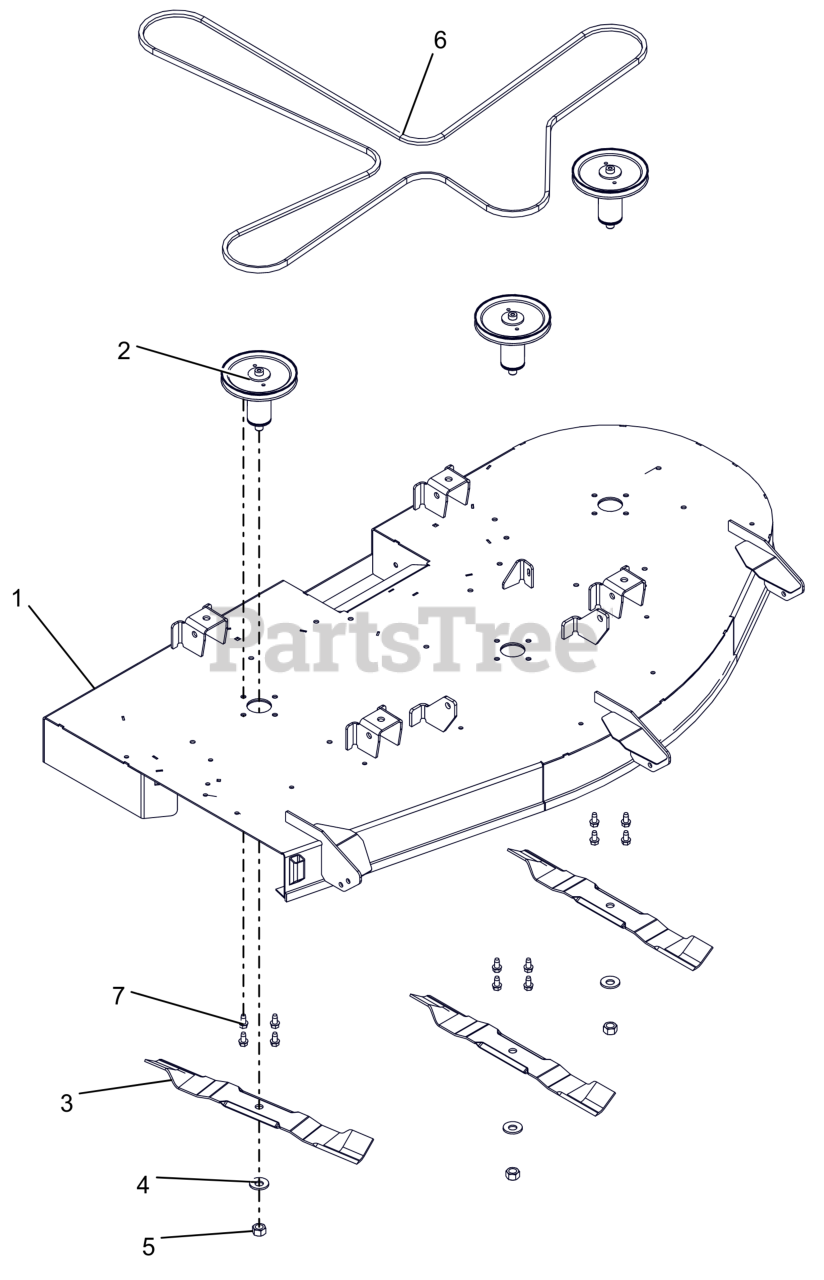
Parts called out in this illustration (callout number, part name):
1	KIT, ARIENS DECK 60" WITH DECALS
2	KIT, DECK SPINDLE ASM-60
3	BLADE, 21" 35 DEG
4	WSHR-BLVL .669X1.535X.138
5	NUT-STD .625-18 ZCC
6	BELT, HA
7	SCR,TAP .375-16X.75 HWH TR ZCC
